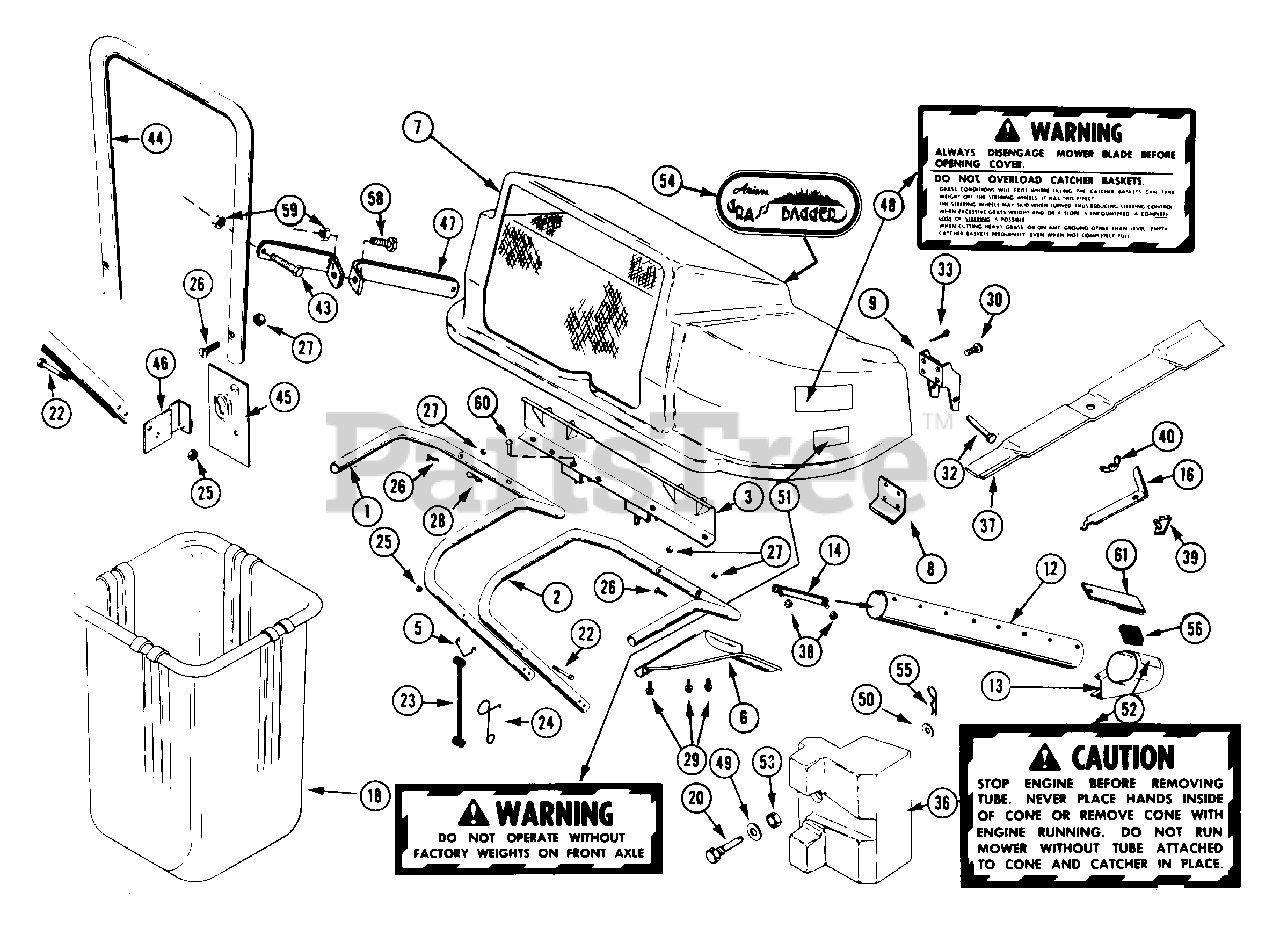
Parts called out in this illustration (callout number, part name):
1	TUBE L.H. SUPPORT
2	TUBE R.H. SUPPORT
6	SUPPORT TUBE
7	GRASS CATCHER COVER ASSEMBLY
8	RETAINER
12	TUBE BLANK
13	CONE ASSEMBLY
16	STRAP CONE
20	STUD-WEIGHT
22	BLT-HEX .25-20X2.25 GR2
23	BATTERY STRAP
24	HOOK
25	NUT-LK-CTR .250-20 PL
26	SCR-MCH .31-18X1.50 CROVCNTRS
27	NUT-LK-NYL.312-18 PL
28	PIN-HAIR INT .08X.38X1.42 YWZC
29	BLT-SERHFWH .25-20X.50 PL
30	BLT-SCRHFWH .25-20X.62 PL
32	CLEVIS PIN
33	PIN-COTR .06X.50
37	MOWER BLADE
38	NUT-LK-FLG .250-20 PL
39	CLIP CONE
40	NUT-WING W/INSERT .312 - 18
43	BLT-HEX .31-18X1.50 PL GR2
44	BAR SUPPORT
45	BRACKET ADAPTER
46	BRACKET MOUNTING
47	BRACKET - ADJUSTMENT
48	WARNING DECAL
49	WSHR-FL-STL .438X1.0X.083 PL
50	WSHR-FL-STL .511X1.441X.125 PL
51	WARNING DECAL
52	CAUTION DECAL
53	NUT-LK-CTR .50-13
54	DECAL-GRASS BAGGER
55	PIN-HAIR INT .09X.188 PL
56	HOOK FASTENER
57	RVT-TBLR .187X.281 OV ST PL
58	BLT-HEX .31-18X2.75 PL GR2
59	NUT-LK .312-18 GR A PL
60	CLEVIS PIN
61	ATTACHING STRAP
